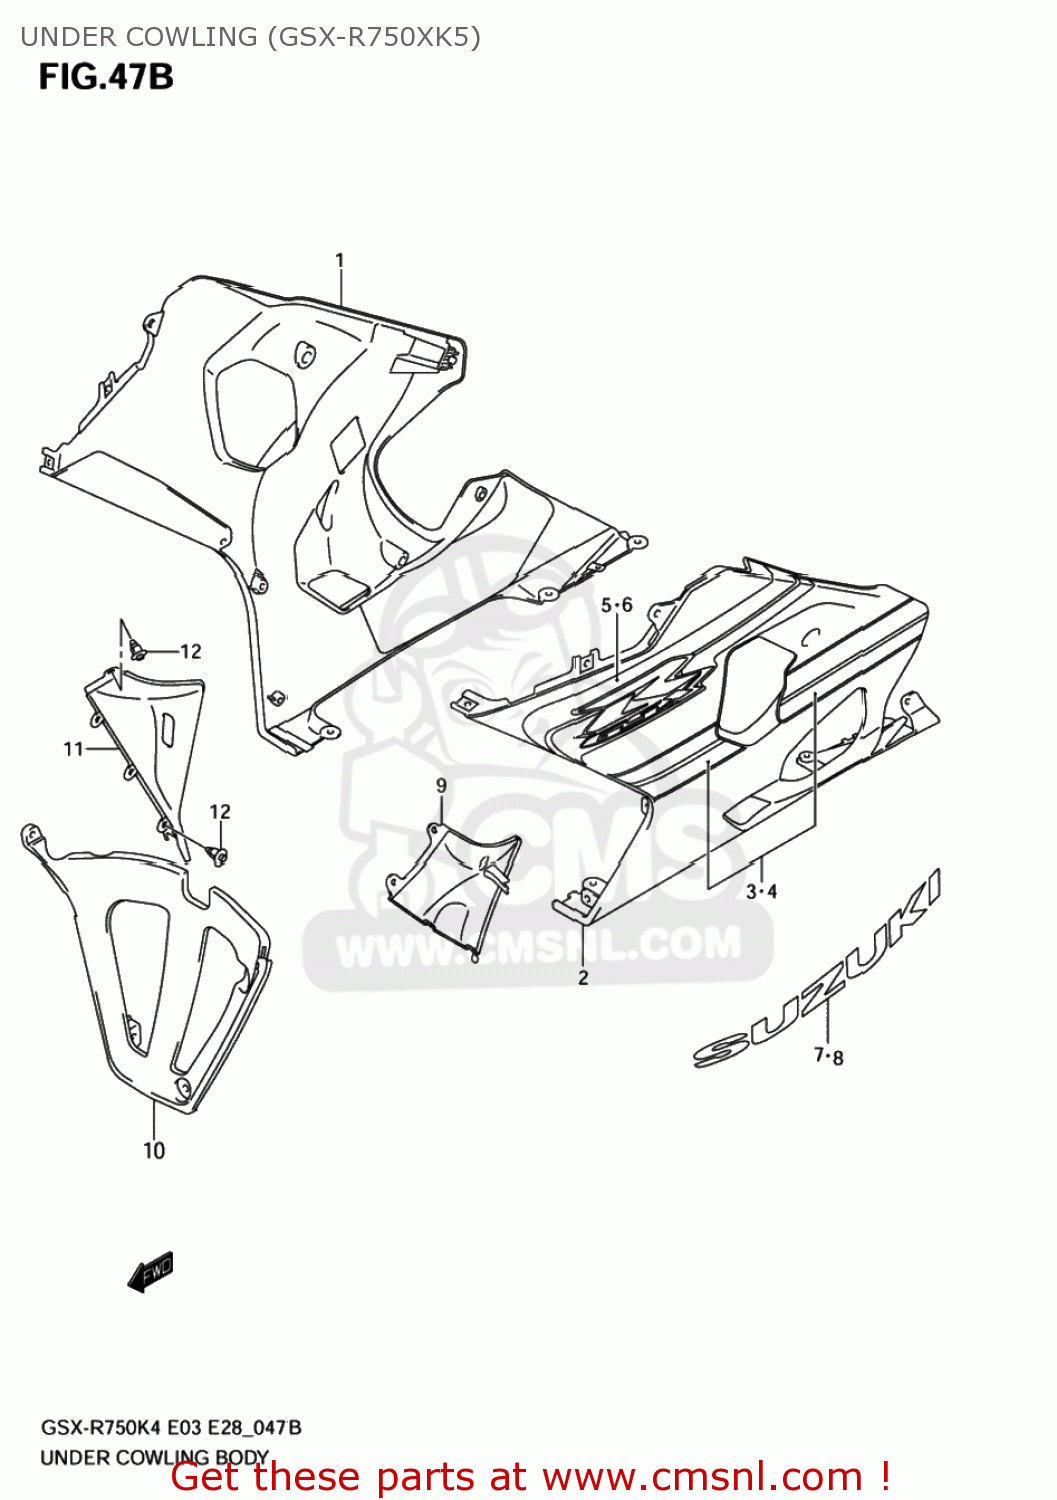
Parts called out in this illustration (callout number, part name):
1	COWLING ASSY,UNDER,R
2	COWLING ASSY,UNDER,L
3	TAPE SET,UNDER COWLING,R
4	TAPE SET,UNDER COWLING,L
5	TAPE,UNDER COWL,R
6	TAPE,UNDER COWL,L
7	EMBLEM,R
8	EMBLEM,L
9	COWLING,UNDER INNER,L
10	COWLING,UNDER CTR
11	COWLING,UNDER INNER,R
12	CLIP(BLACK)
